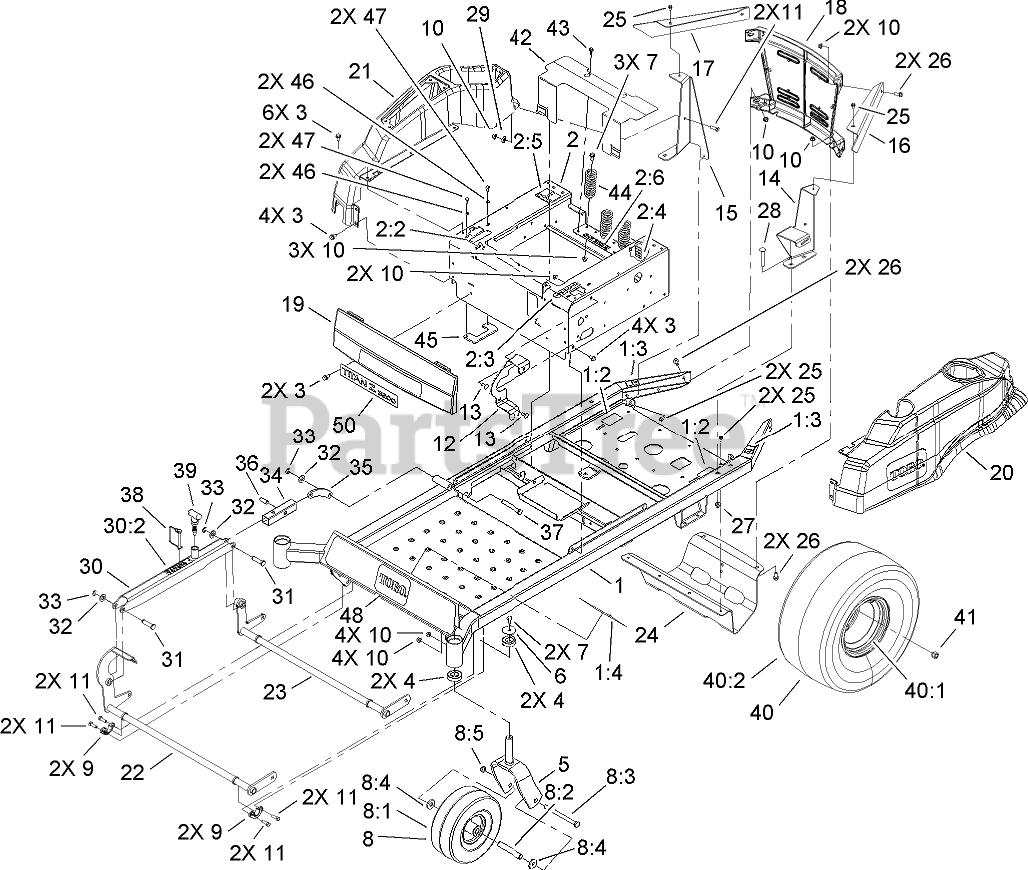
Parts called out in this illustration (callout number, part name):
1	FRAME ASM
1:2	DECAL-DRIVE RELEASE
1:3	DECAL-WARNING
1:4	DECAL-SAFETY WARNING
2	SEAT BOX ASM
2:2	DECAL-CONTROL, MOTION
2:3	DECAL-CONTROL, BRAKE
2:4	DECAL-FUSE BLOCK
2:5	DECAL-ROUTING, BELT
2:6	DECAL-DANGER
3	SCREW-HWHTF
4	BEARING-BALL
5	CASTER FORK ASM
6	WASHER
7	SCREW-HHF
8	CASTER WHEEL ASM
8:1	WHEEL-CASTER
8:2	BUSHING-SPANNER
8:3	SCREW-HH
8:4	WASHER
8:5	NUT-LOCK, NI
9	BEARING-FLANGE
10	NUT-HF, NI
11	SCREW-HH
12	BRACKET-TANK MOUNT
13	SCREW-CARR
14	BRACKET-REAR TANK, LH
15	BRACKET-REAR CONSOLE, RH
16	GUARD-ENGINE, LH
17	GUARD-ENGINE, RH
18	CASTING-REAR
19	PANEL-FRONT
20	FENDER-LH
21	FENDER-RH
22	FRONT SHAFT ASM
23	REAR SHAFT ASM
24	GUARD-MUFFLER
25	SCREW-HWH
26	SCREW-HHF
27	NUT-HF, NI
28	SCREW-CARR
29	WASHER-FLAT
30	HEIGHT ADJUST ASM
30:2	DECAL-CUT HEIGHT
31	PIN-CLEVIS
32	WASHER-FLAT
33	RING-RETAINING, EXTERNAL
34	STOP-HEIGHT ADJUST
35	ARM-FLOAT LINK
36	PIN-PIVOT
37	PIN-CLEVIS
38	PIN-HITCH
39	PIN-SPRING
40	4 PLY WHEEL AND TIRE ASM
40:2	TIRE-4 PLY
41	NUT-LUG
42	COVER-HYDRO FAN
43	SCREW-HHF
44	SPRING-COMPRESSION
45	STOP-MOTION CONTROL
46	WASHER-SPRING
47	SCREW-HH
48	DECAL-FRONT PANEL, TORO
